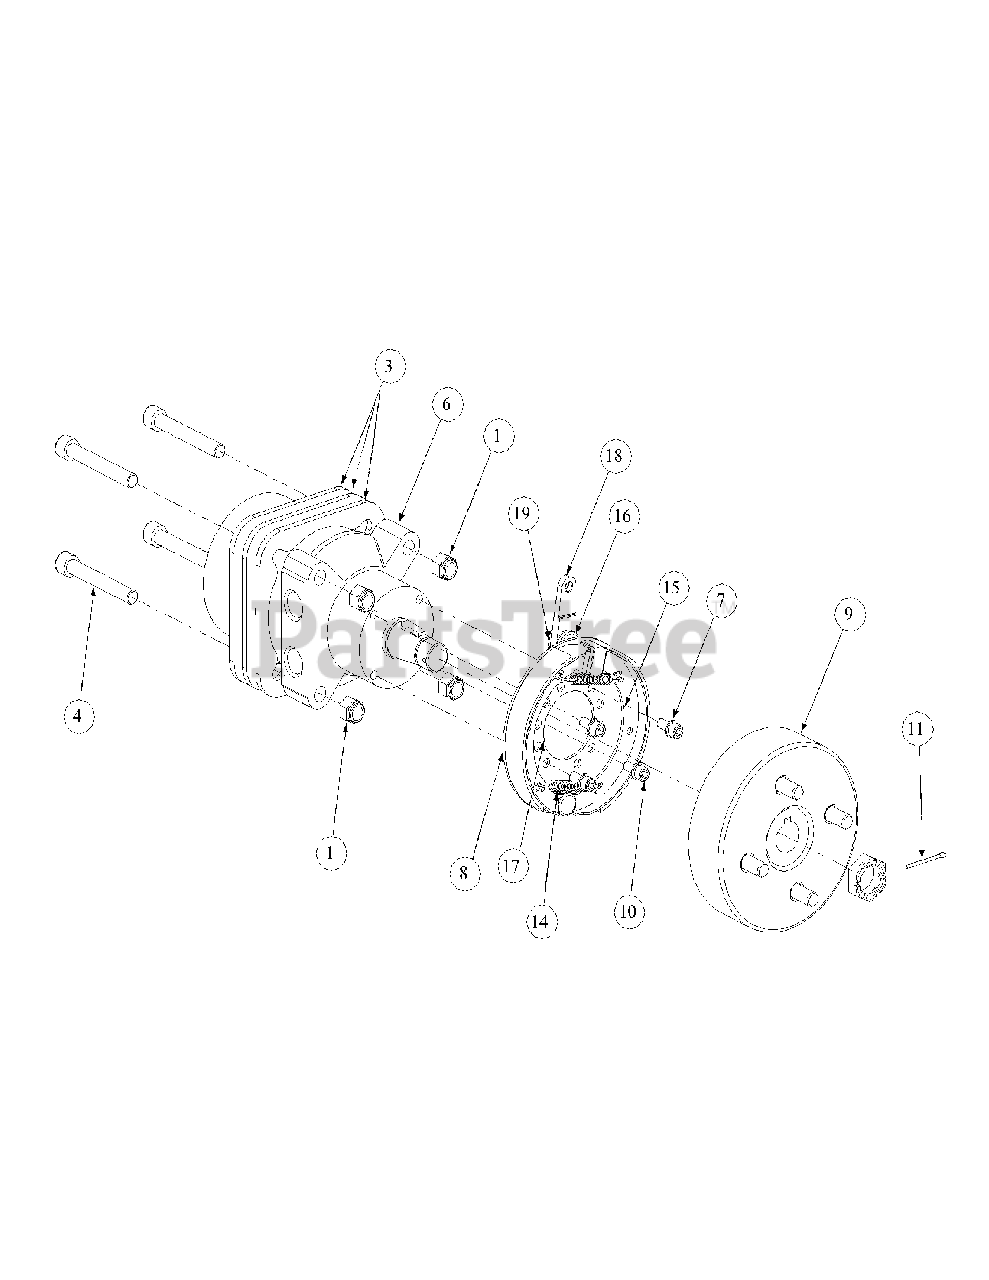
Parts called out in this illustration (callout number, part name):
1	Lock Nut, Nylon Insert, 1/2-13
3	Motor Spacer
3	Motor Spacer .750
3	Motor Spacers .750
4	Socket Head Capscrew, 1/2-13; 6-1/2
5	Hyd. Motor, Parker Left Hand Assembly w/Brake & Drum
6	Hyd. Motor, Parker Right Hand Assembly w/ Brake & Drum
7	Lock Washer, 5/16
8	Brake Assembly w/Line
9	Hub and Drum Assembly w/Studs
10	Capscrew w/Socket, 5/16-18 x 3/4
11	Cotter Pin 1/8 x 1-1/2
